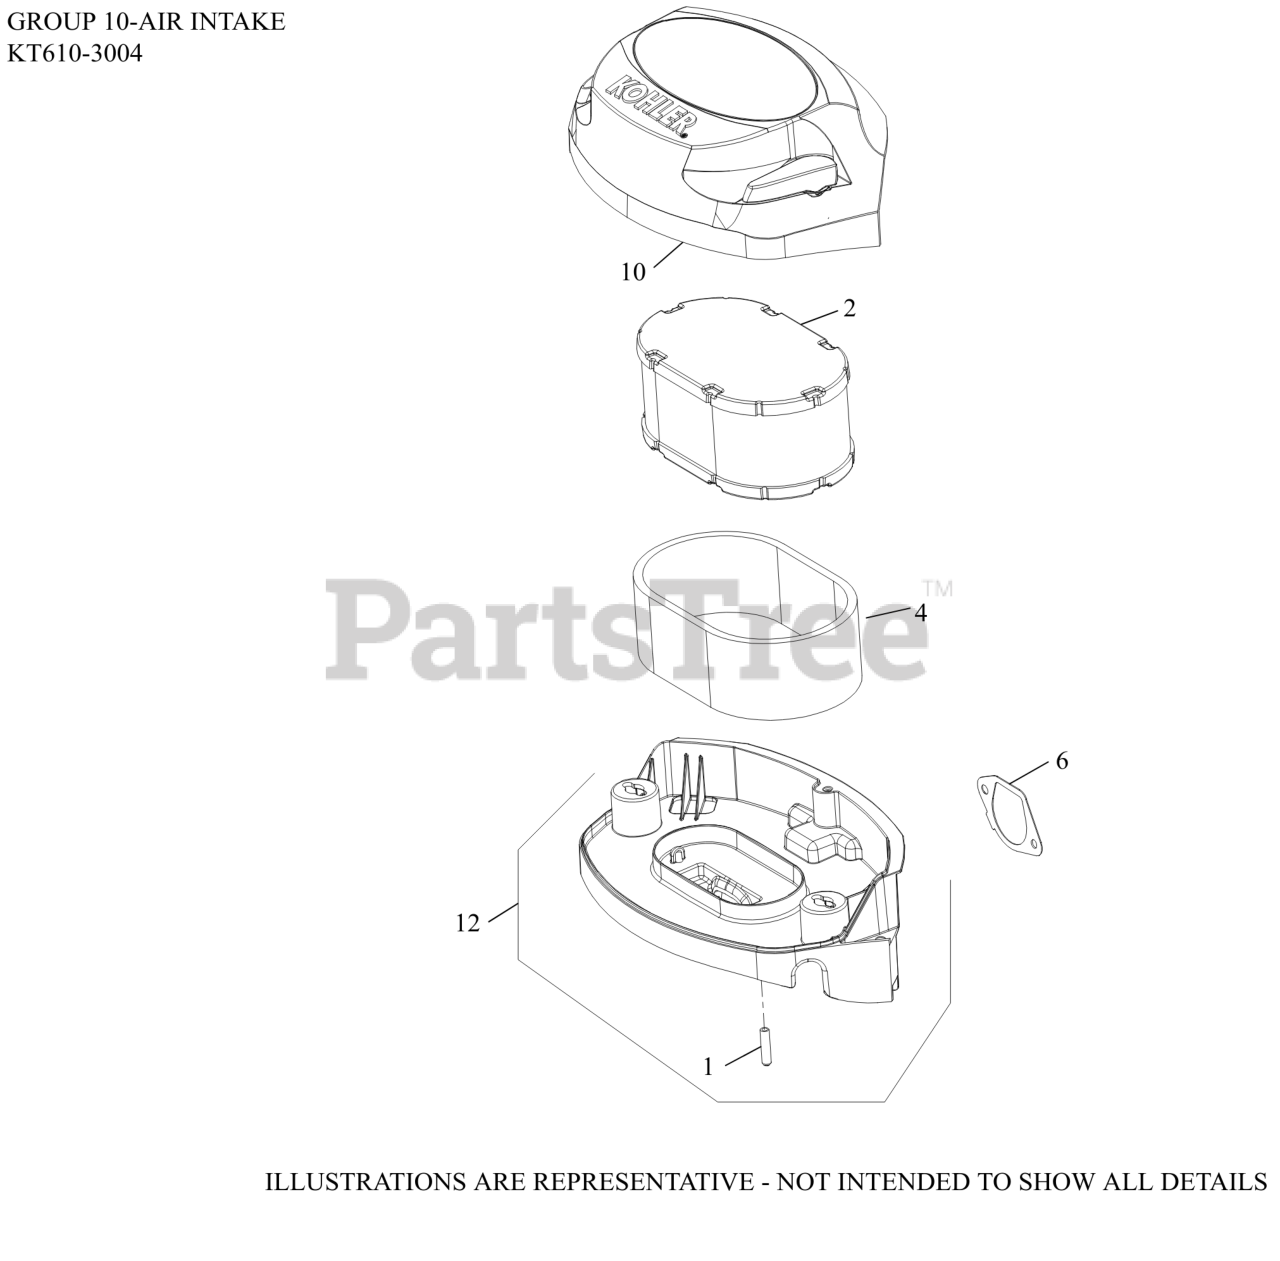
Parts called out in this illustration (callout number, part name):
1	CAP, MASKING
2	ELEMENT, AIR FILTER
4	ELEMENT, PRE-CLEANER
6	GASKET, AIR CLEANER BASE
10	COVER ASSY, AIR CLEANER
12	BASE ASSY, AIR CLEANER
